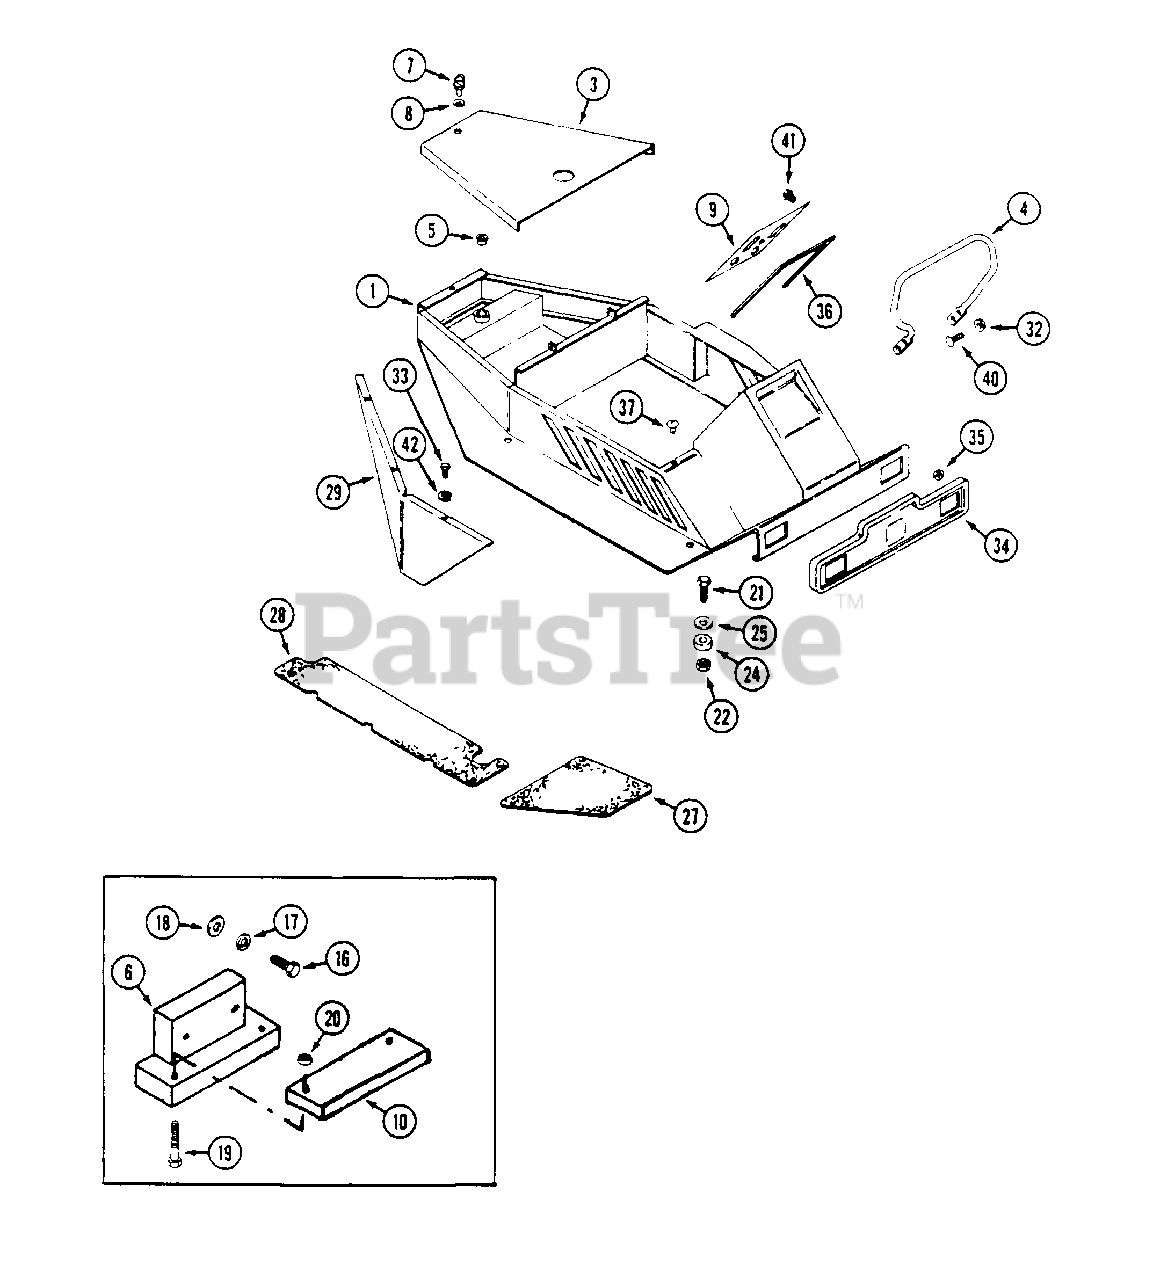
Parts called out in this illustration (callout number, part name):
1	BODY
5	BEARING - rear wheel fork
6	WEIGHT - tail
7	STUD - fastener
8	GROMMET - fastener
9	PANEL - dash
10	WEIGHT - tail 13 lb.
16	BOLT - 5/16" - 18 x 1"
17	LOCKWASHER - 6/16"
18	WASHER - 5/16"
19	BOLT - 3/8" - 16 x 4-1/2"
20	NUT - 3/8" - 16 flange lock
21	BOLT - 1/2" - 13 x 3"
22	NUT - 1/2" lock
24	MOUNT - body, rubber
25	WASHER - mount, body
27	PAD - footrest, front L.H.
28	PAD - footrest, rear L.H.
32	NUT - 5/16" - 18 flange lock
33	BOLT - 1/4" - 20 x 3/4 self-tap
35	NUT - #8 - 32 flange lock
36	TRIM - 28"
37	BUMPER - nylon
40	BOLT - 5/16" - 18 x 3/4" carriage
41	SCREW - #12 x 1/2"
42	LOCKWASHER - 1/4"
